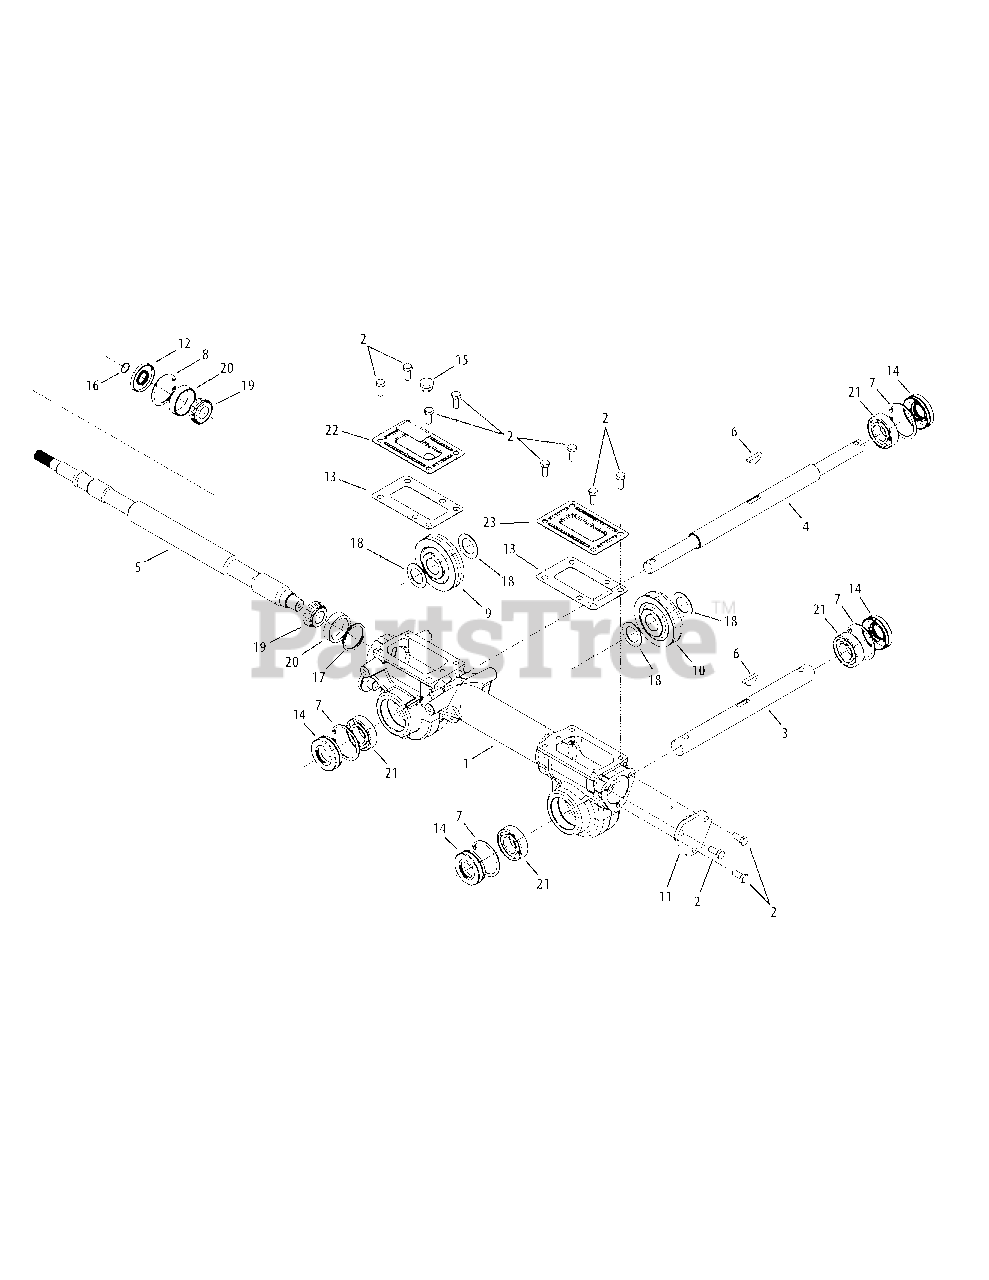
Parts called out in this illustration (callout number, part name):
1	Housing, Transmission
2	Hex Screw, 5/16-18, .75, Gr5
3	Shaft, Tiller
4	Shaft, Wheel
5	Shaft, Worm
6	Key, Hi Pro .25 x 1.062
7	Retaining Ring
8	Retaining Ring, Int
9	Worm Gear, 61t, RH
10	Worm Gear, 30t, LH
11	Bearing Cover
12	Seal, Oil, .750 Shaft x 1.783 Bore
13	Gasket, Gear Housing
14	Seal, Oil, 1.00 Shaft x 2.00 Bore
15	Rubber Plug, Oil
16	Wire Ring
17	Washer, Flat, 1.50 x 1.75 x .062
17	Washer, Flat, 1.50 x 1.75 x .005
17	Washer, Flat, 1.50 x 1.75 x .03
17	Washer, Flat, 1.50 x 1.75 x .010
18	Washer, Flat, 1.010 x 1.56 x .060
19	Cone Bearing
20	Bearing Cup
21	Ball Bearing
22	Cover, Transmission
23	Cover, Transmission
